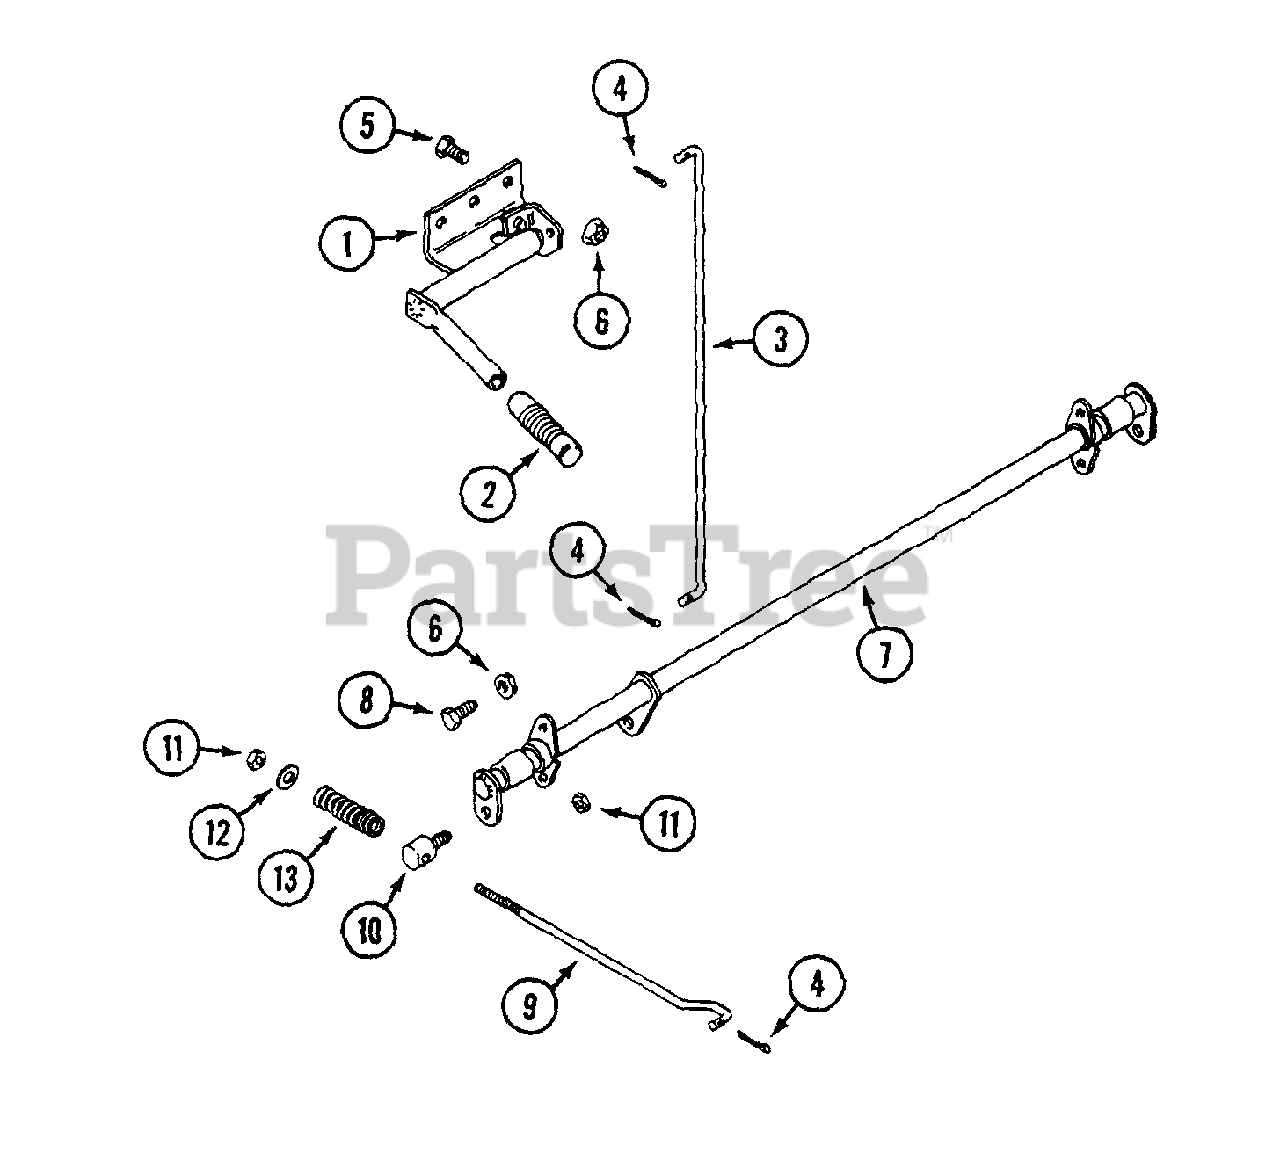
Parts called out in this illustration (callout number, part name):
1	LEVER - brake
2	GRIP - handle
3	ROD - brake lever
4	PIN - cotter 3/32" x 1"
5	BOLT - 1/4" - 20 x 3/4"
6	NUT - 1/4" - 20 flange lock
7	SHAFT - brake
8	BOLT - 1/4" - 20 x 5/8"
9	ROD - brake caliper
10	COLLAR - caliper rod
11	NUT - 1/4" - 20 lock
12	WASHER - 5/16" x 3/4"
13	SPRING - compression
